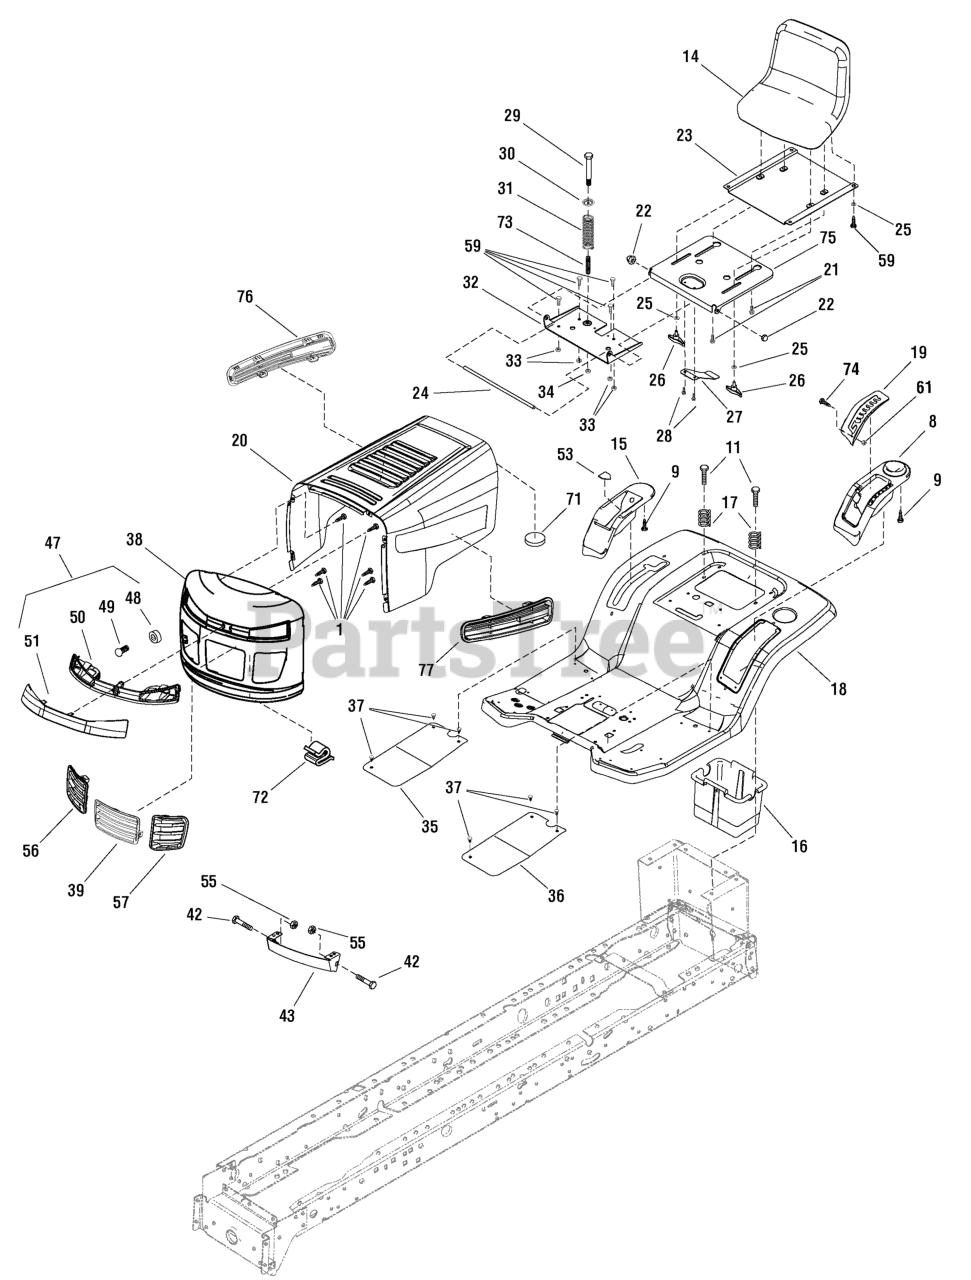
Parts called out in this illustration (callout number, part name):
1	SCREW, Thread Forming
8	POD, With Cup Holder
9	SCREW, Thread Cutting 1/4-20
11	CAPSCREW, 5/16-18 x 3/4
14	SEAT, Low Back
15	POD, With Compartment
16	CONTAINER, Battery
17	SPRING, Compression
18	DECK, Seat
19	PLATE, Index
21	BOLT, Shoulder 5/16-18 x 5/8
22	CAP, Push On
23	SEAT PLATE
24	ROD, Pivot
25	WASHER, Flat, 5/16
26	BOLT, Wing 5/16-18 x 1/2
27	LEAF SPRING
28	SCREW, 1/4-14 x 3/8
29	BOLT, Shoulder 1/4-20 x 5/16
30	WASHER, Cup
31	SPRING, Compression
32	BRACKET, Seat Pivot
33	NUT, Nylock 5/16-18
34	NUT, Hex Flange, 1/4-20
35	MAT, Molded Right
36	MAT, Molded Left
37	FASTENER, Panel
39	INSERT, Center Grille
42	BOLT, Shoulder
43	BRACKET, Lower Pivot
47	HEADLIGHT ASSEMBLY
48	SOCKET, Lamp
49	BULB, 12.8V
50	HOUSING, Light
51	LENS, Light
53	INDICATOR, Cutting Height
55	NUT, Centerlock, 3/8-16
56	INSERT, Right Grille
57	INSERT, Left Grille
59	BOLT, Hex, 5/16-18 x 5/8
61	NUT, Flange Lock 1/4-20
73	SPRING, Brake Compression
74	SCREW, Shoulder #10-24
75	SUPPORT, Seat
76	INSERT, Right Hood
77	INSERT, Left Hood
